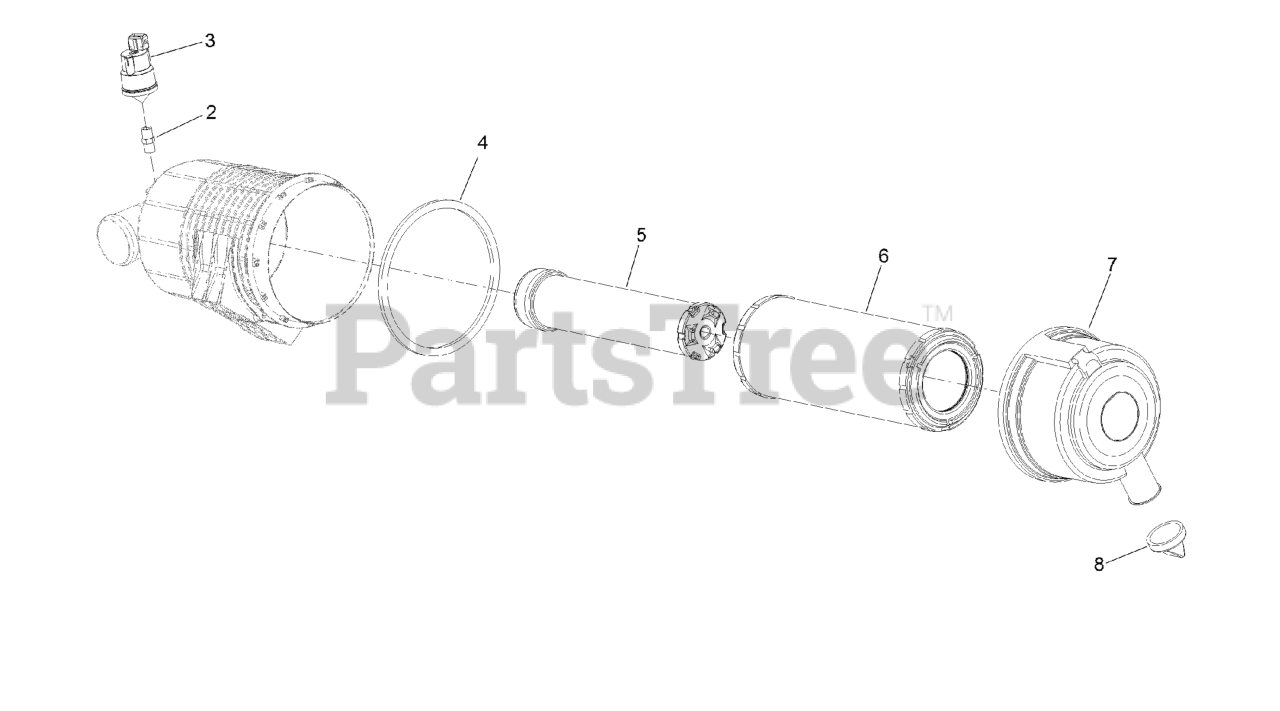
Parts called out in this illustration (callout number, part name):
2	NIPPLE-PIPE
3	INDICATOR-MINI
8	VALVE-VACUATOR
